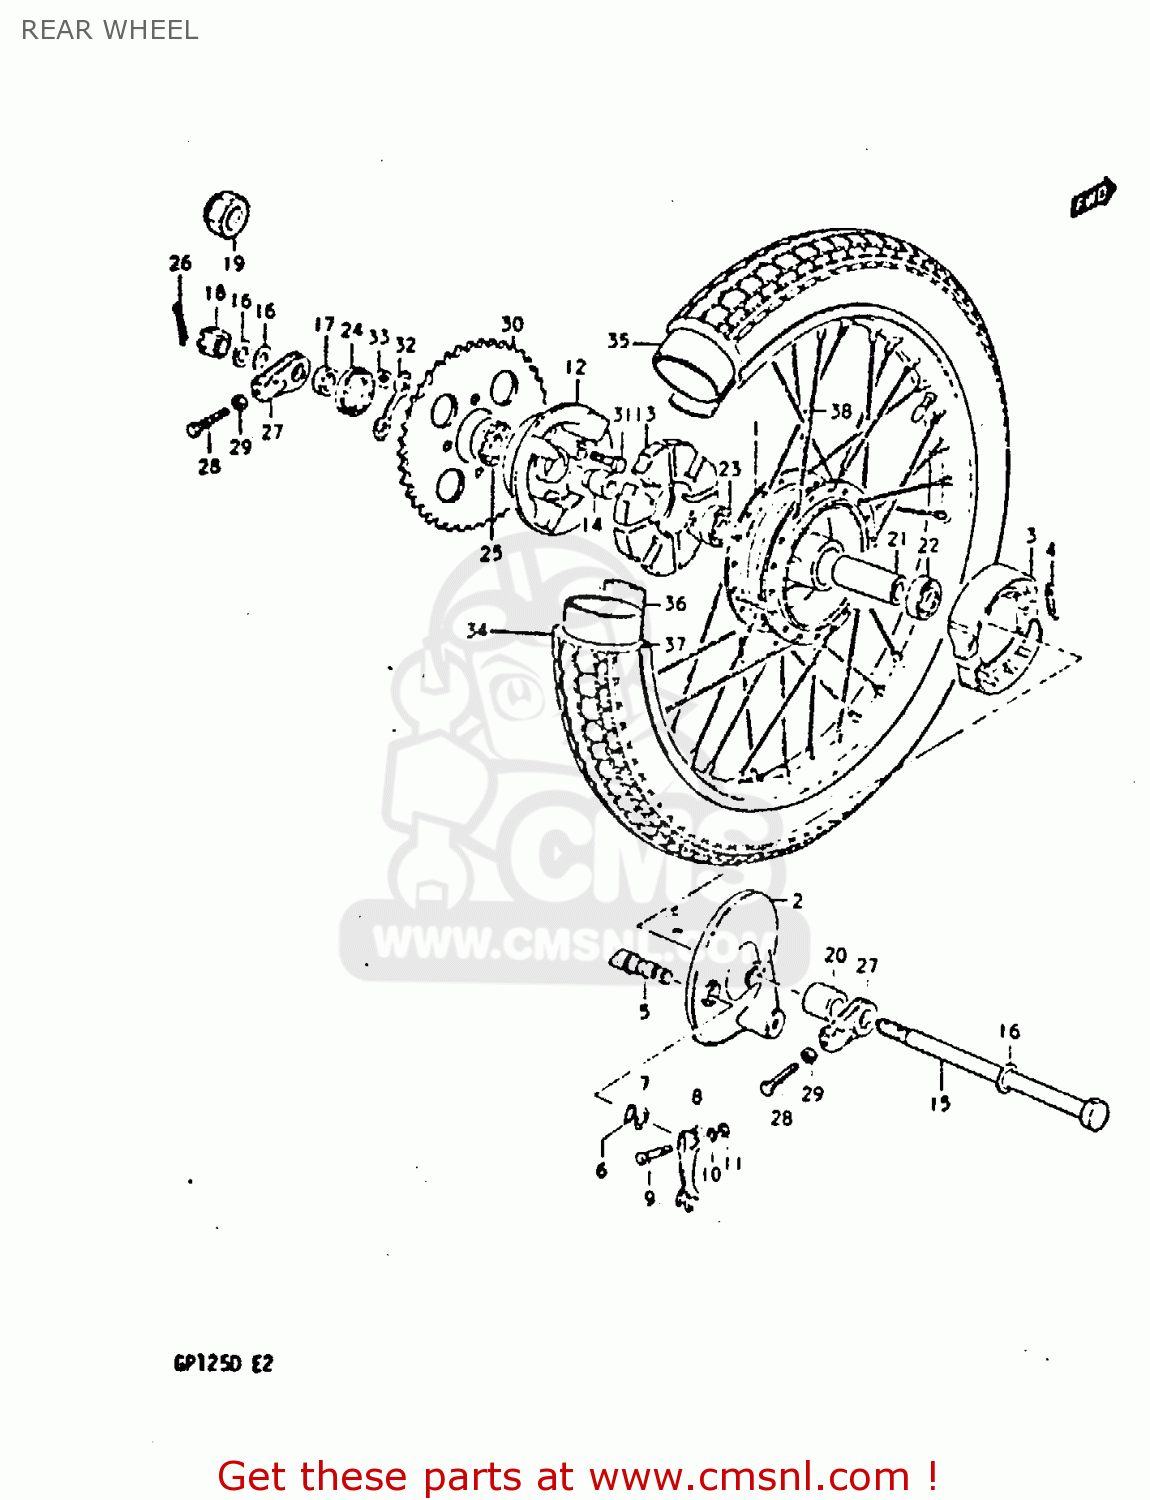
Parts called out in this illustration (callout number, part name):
1	HUB,REAR WHEEL
2	PANEL, REAR WHEEL
3	SHOE,BRAKE
4	SPRING(L:34)
5	CAM,FRONT BRAKE
6	O-RING (D:2.4 ID:13.8)
7	WASHER (14.5X22X1.6)
8	LEVER,RR BRAKE CAM
9	BOLT(6X33)
10	WASHER
11	NUT
12	DRUM,RR SPROCKET
13	ABSORBER ASSY,HUB SHOCK
14	RETAINER,RR SPROCKET MTG
15	AXLE,REAR
16	WASHER
17	SPACER(15X28X19)
18	NUT
20	SPACER(15.2X26X33)
21	SPACER(15.3X21.7X63)
22	BEARING
23	BEARING
24	SEAL,OIL(28X47X7)
25	Bearing
26	COTTER PIN
27	ADJUSTER,CHAIN
28	BOLT
29	NUT
30	SPROCKET,REAR
31	BOLT(8X33.5)
32	WASHER
33	NUT
34	TIRE
35	TUBE,INNER
36	PROTECTOR,INNER TUBE
37	RIM,REAR WHEEL
38	SPOKE SET,REAR
